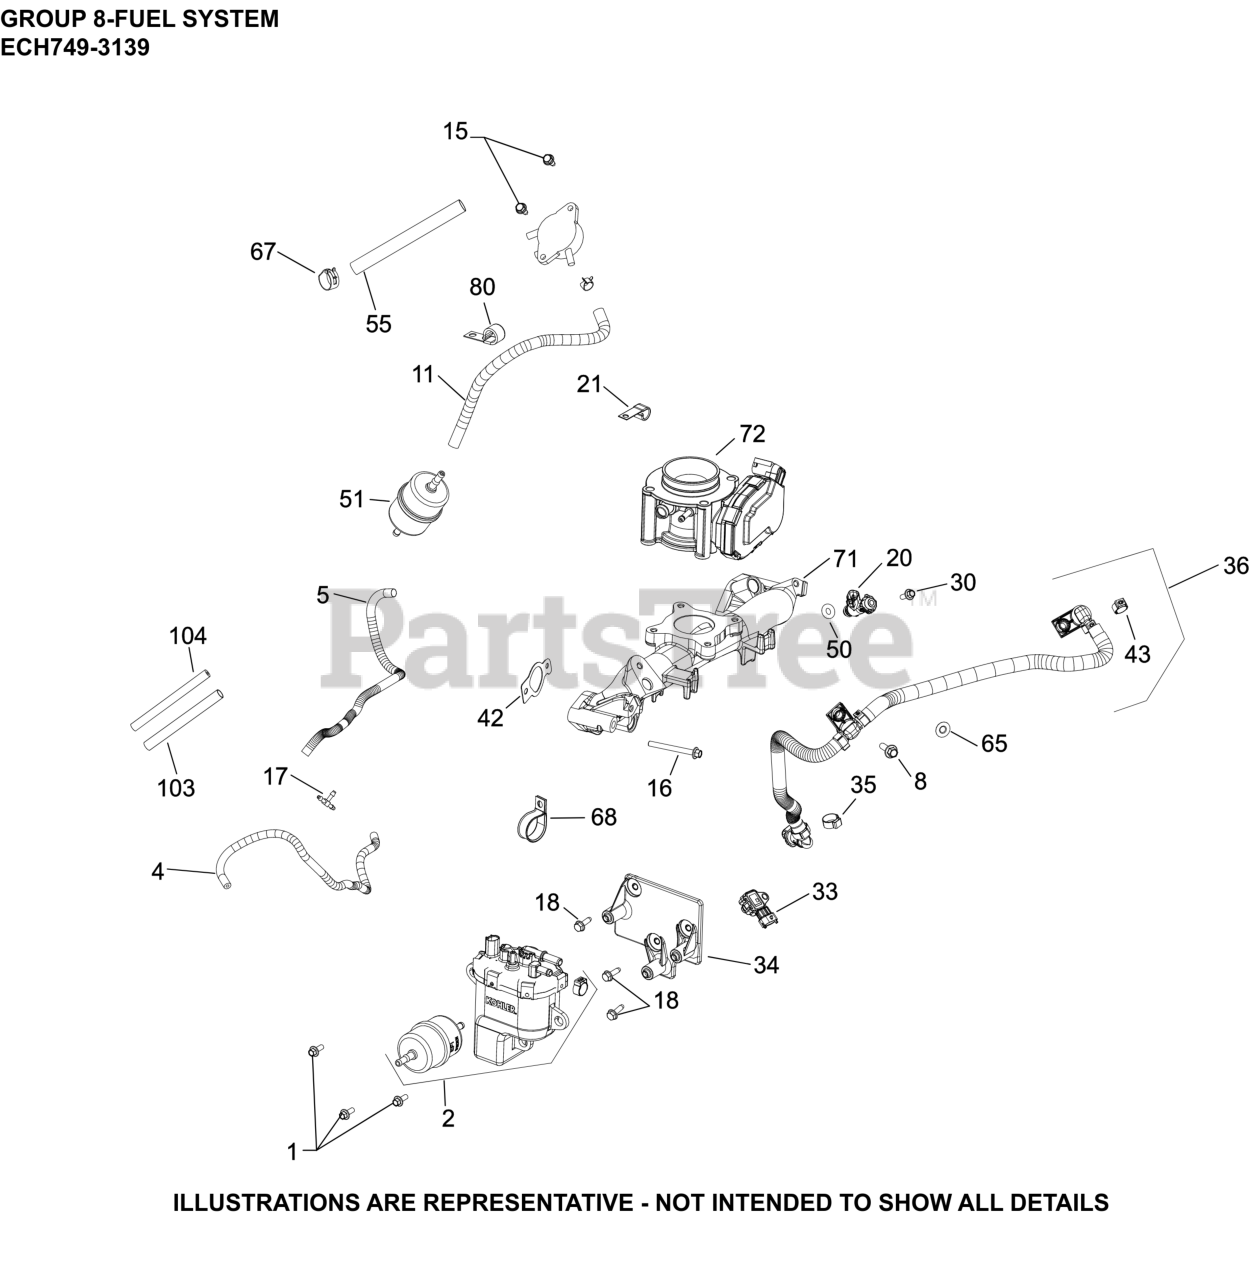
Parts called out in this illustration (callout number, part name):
1	SCREW, FLG M6X1.0X16
2	KIT, FUEL PUMP MODULE
4	HOSE, EVAPORATIVE (15.0)
5	SLEEVE, ANTI-ABRASION
8	SCREW, FLG M6x1.0x20
11	HOSE,LW PERM.FUEL 24.00"-USE 25 111 81-S
15	SCREW, THREAD FORMING
16	SCREW, FLG M6X1.0X60
17	TEE CONNECTOR
18	SCREW, THREAD FORMING
20	INJECTOR, FUEL
21	CLIP, CABLE
30	SCREW, FLG M6X1.0X16
33	SENSOR, T-MAP
34	BAFFLE, FUEL MODULE
35	CLAMP, HOSE
36	FUEL HOSE ASSEMBLY,ECH680-ECH749
42	KIT, INTAKE MANIFOLD GASKET
43	CLAMP, OETIKER
50	KIT, FUEL INJECTOR O-RING
51	FILTER, FUEL
55	SLEEVE, ANTI ABRASION -USE 25 431 12-S
55	SLEEVE, ANTI ABRASION-USE 25 431 12-S
65	CLIP, RETAINER
67	CLAMP, SPRING HOSE
68	CLAMP, INSULATED
71	MANIFOLD, INTAKE - ETB HORIZONTAL
72	BODY, ELECTRONIC THROTTLE ASM 30 DIA
80	CLIP, CABLE (KM)
103	SLEEVE, ANTI-ABRASION
104	HOSE, EVAPORATIVE (4.5)
